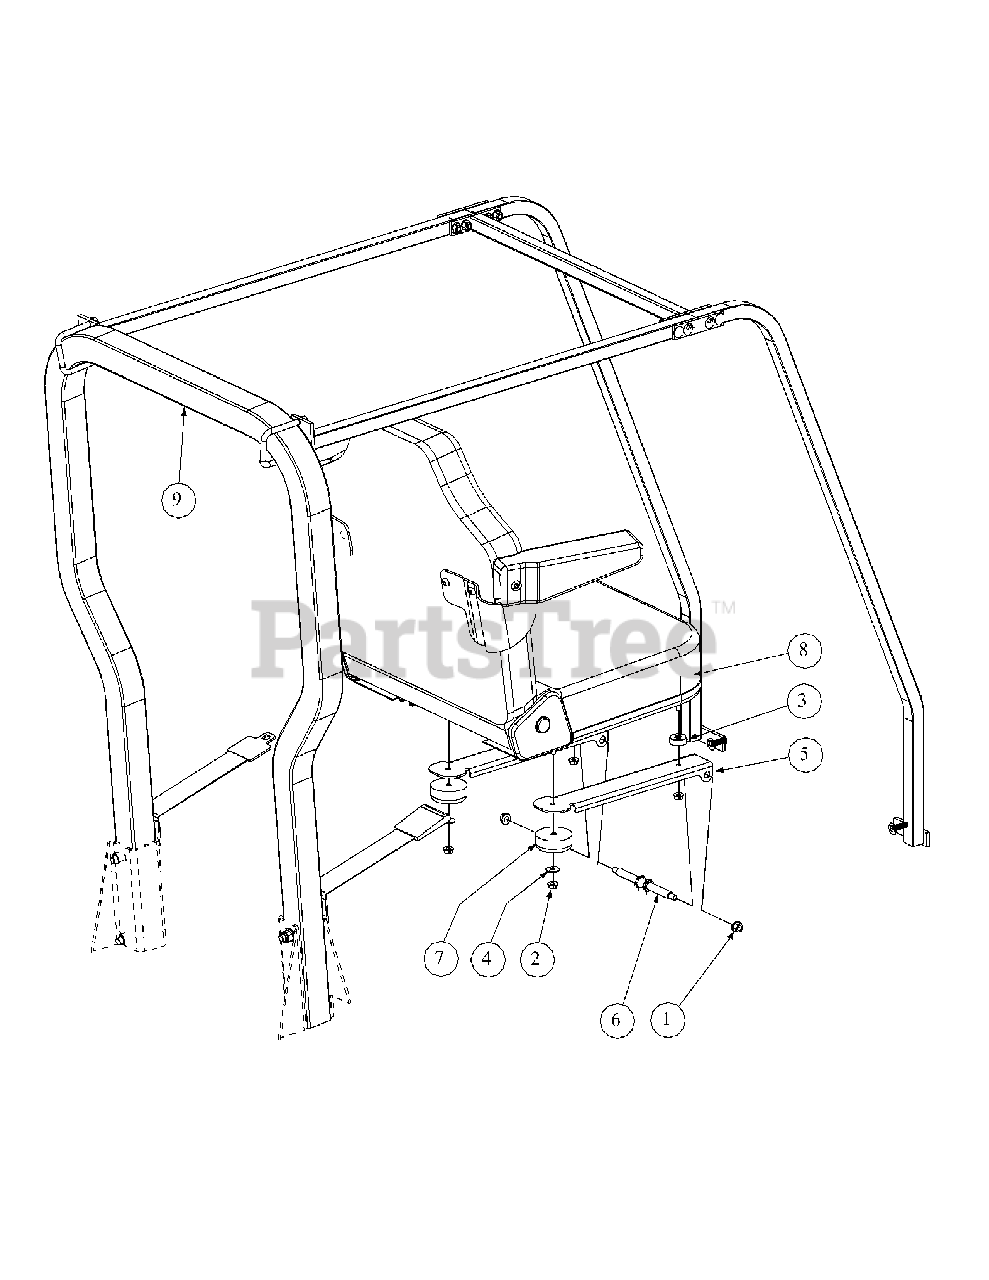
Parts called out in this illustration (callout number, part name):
1	Nut, Hex 3/8-16 Flange Lock
2	Lock Nut, Hex Flange, 5/16-18
3	Spacer, 0.345 ID x 1.50 OD x .41
4	Washer, .325 ID x .930 OD x .045
5	Mounting Bracket, Seat
6	Shoulder Screw, .50x2.345, 3/8-16
7	Grommet, 2.5 OD x 1.0 Long
8	Adjustable Seat, Black embossed, Forward Fold
9	ROPS Assembly
